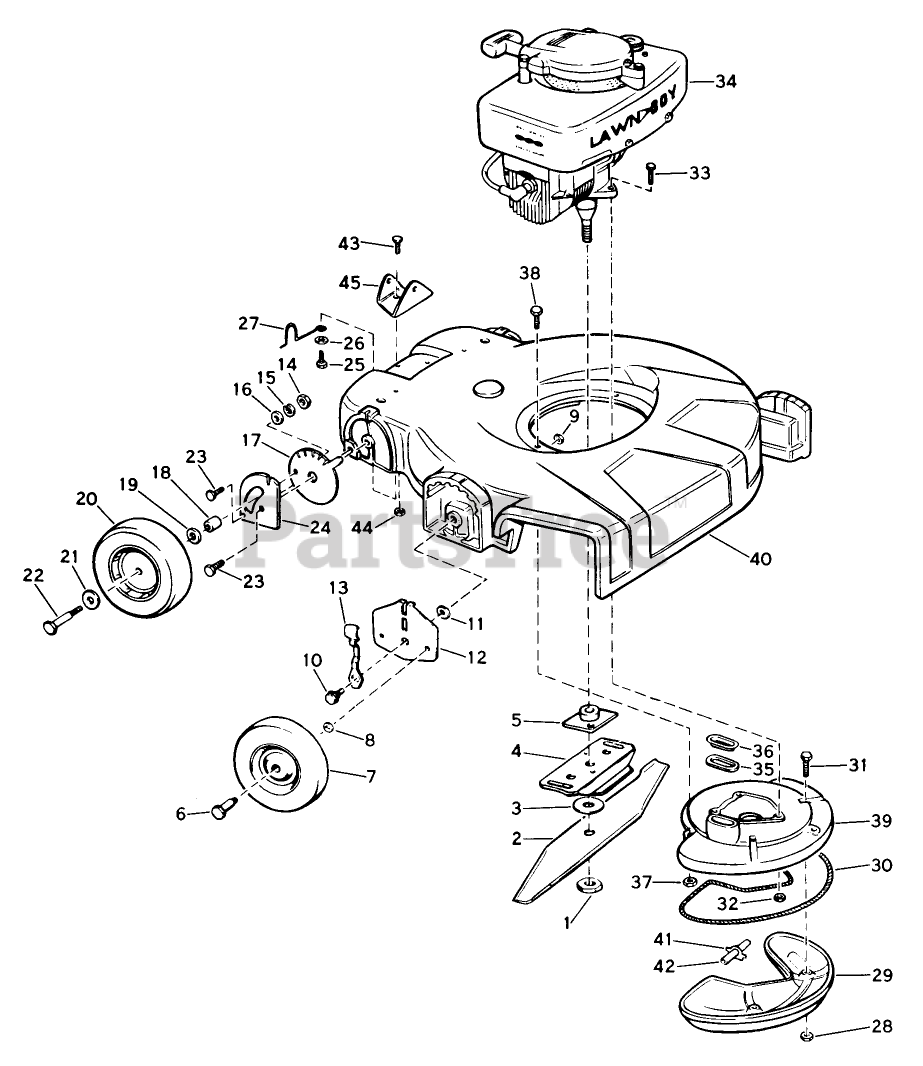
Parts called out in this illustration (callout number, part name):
1	NUT-BLADE
5	PLATE AND COLLAR ASM
6	BOLT WHEEL
8	WASHER WROUGHT
14	Nut-Hex
15	WASHER, LOCK
17	Lever-Wheel
18	Spacer-Wheel
22	Bolt-Wheel
24	Plate-Wheel Height Adj.
27	Spring-Wheel Height Adj.
28	LOCKNUT E
34	Engine-Model C-18
41	Gasket-Internal Tube
42	Tube-Internal Muffler
44	STOP NUT
